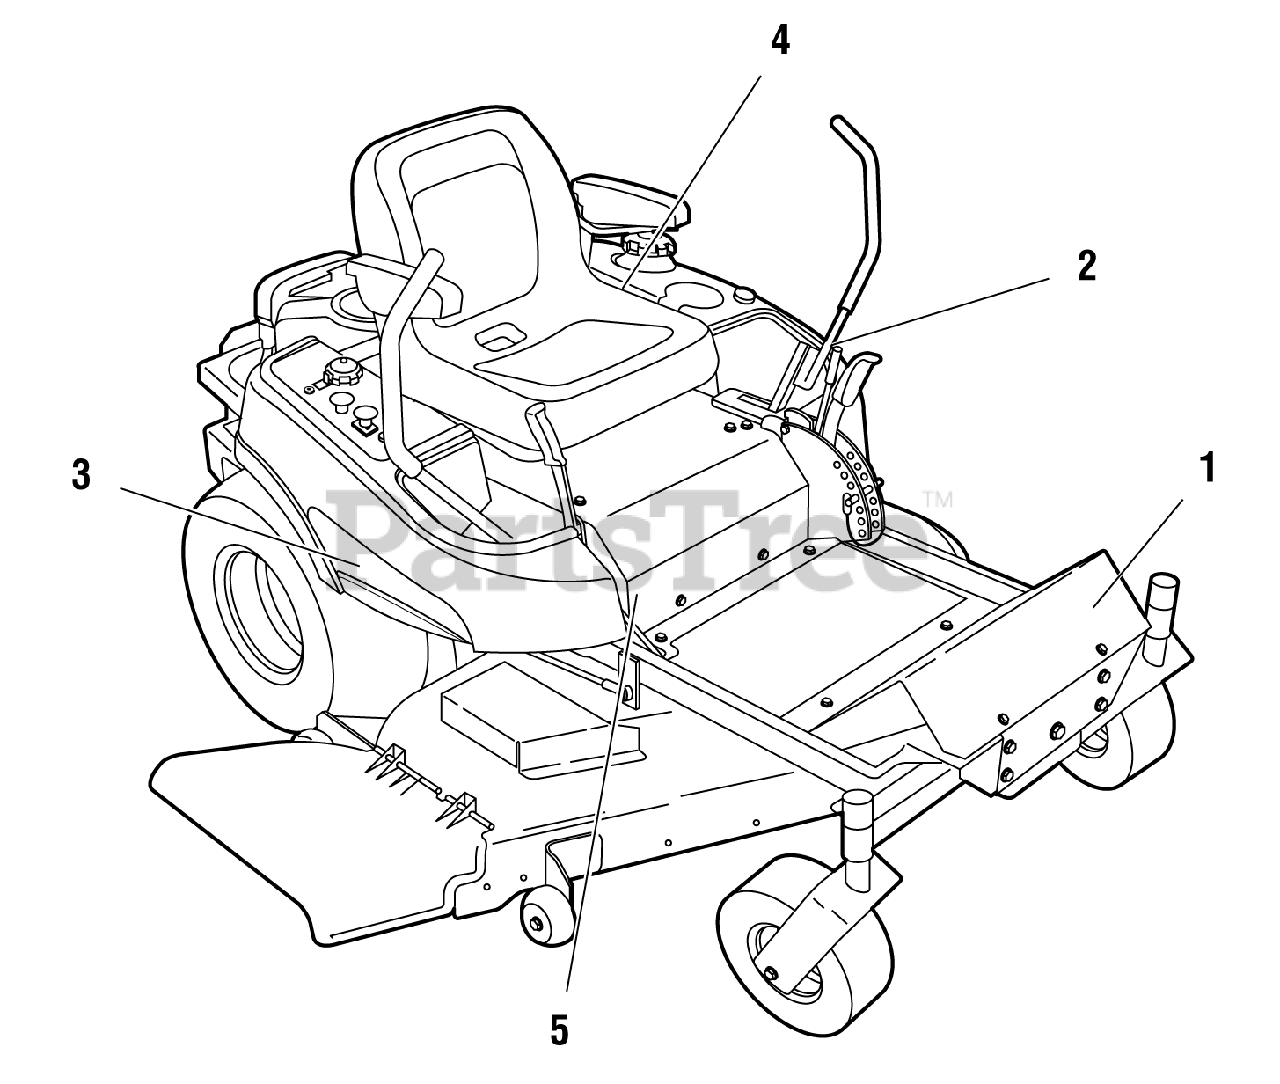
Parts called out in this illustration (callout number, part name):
1	DECAL, SNAPPER-SILVER/BLACK 8.5LG
2	DECAL, BADGE, LH, SNAPPER
3	DECAL, BADGE, RH, SNAPPER
4	DECAL, TOUCH UP PAINT SNAPPER
5	DECAL, 355Z
5	DECAL, 360Z
5	DECAL, 365Z
5	DECAL, SNP, ZTX300
